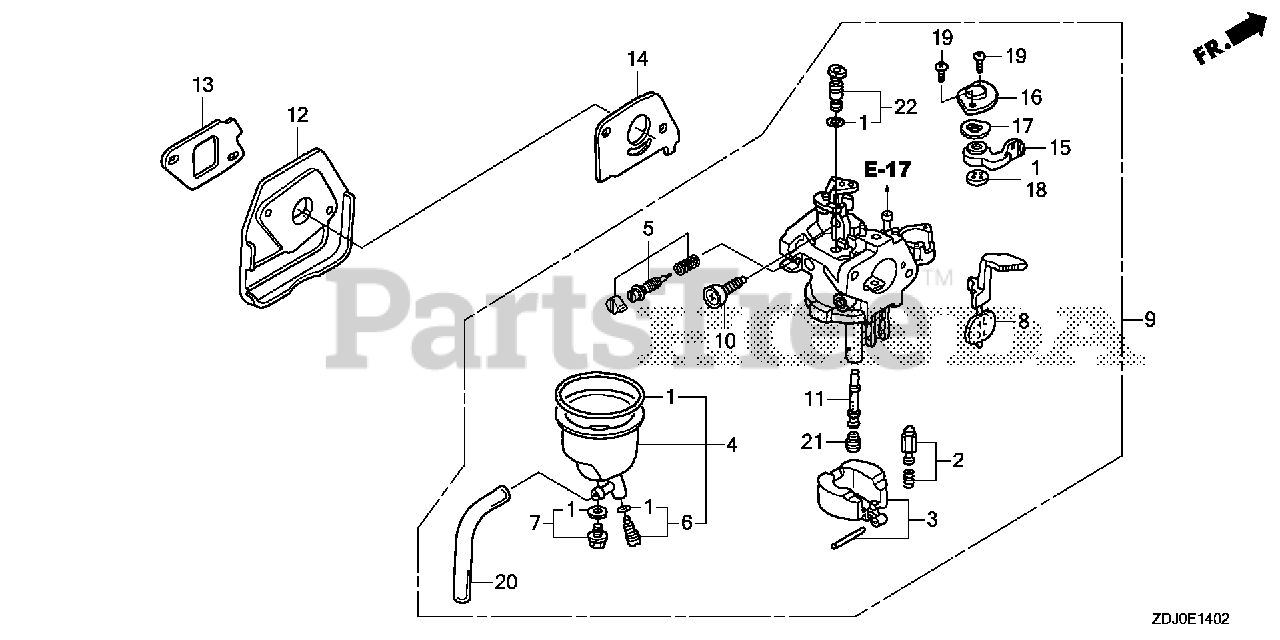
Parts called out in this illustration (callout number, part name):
1	GASKET SET
2	VALVE SET, FLOAT (CARBURETOR NO.) (SEAT NOT INCLUDED)
4	CHAMBER SET, FLOAT
6	SCREW SET, DRAIN (CARBURETOR NO.)
8	CHOKE SET (CARBURETOR NO.)
9	CARBURETOR ASSY. (BF32S A)
10	SCREW, THROTTLE STOP
11	NOZZLE, MAIN
12	INSULATOR, CARBURETOR
13	GASKET, INSULATOR
14	GASKET, CARBURETOR
15	LEVER, PETCOCK
16	PLATE, LEVER SETTING (CARBURETOR NO.)
17	SPRING, PETCOCK LEVER (CARBURETOR NO.)
18	GASKET, VALVE
19	SCREW, PAN (3X6)
20	BULK HOSE, VINYL (3.5X6.5X8000) (9500(95003-05001-60M) (CARBURETOR NO.)
21	JET, MAIN (#55) Use from Engine SN BF22B D.
21	JET, MAIN (#58) Use from Engine SN BF22B D.
21	JET, MAIN (#60)
22	JET SET, PILOT (#38)
